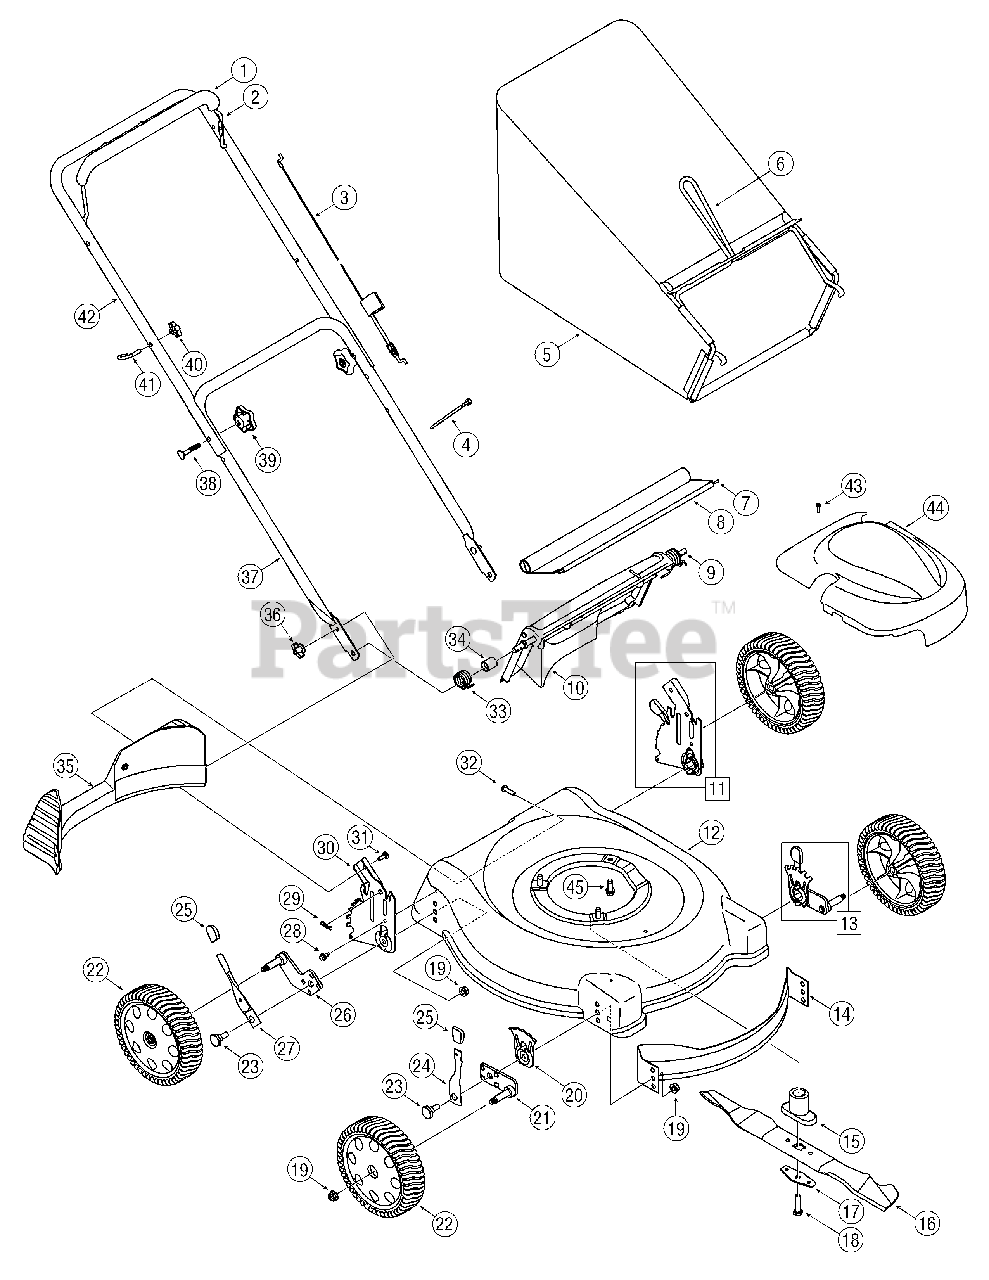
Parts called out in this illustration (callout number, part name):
1	Blade Control Handle Cover
3	Control Cable - 40"
4	Cable Tie
5	Grass Bag Assembly
7	Trailshield Wire
8	Trailshield
9	Rear Door Pivot Rod
10	Rear Discharge Door
11	Handle Bracket Assy - RH
11	Handle Bracket Assy - LH
13	Height. Adj. Assy. Front - RH
13	Height Adj. Assy. Front - LH
14	Front Baffle
15	Blade Adapter
16	Blade
17	Bell Blade Support
18	HH Cap Screw, 3/8-24 x 2.50
19	Flange Lock Nut, 3/8-16
20	Height Adjustment Plate
21	Pivot Arm Assembly - LH
21	Pivot Arm Assembly - RH
22	Wheel, 8 x 2.125 Gray Idle S-Wave
23	Shoulder Screw .500 x .434
24	Spring Lever
25	Height Adjustment Knob
26	Pivot Arm Assembly - LH
26	Pivot Arm Assembly - RH
27	Spring Lever
28	TT Screw 1/4-20 x .625
29	Hairpin Clip
30	Rear Handle Bracket - LH
30	Rear Handle Bracket - RH
31	Carriage Bolt, 1/4-20
32	HL Screw 1/4-15 x 1.00
33	Torsion Spring - LH
33	Torsion Spring - RH
34	Spacer
35	Rear Baffle
36	Wing Nut
38	Carriage Bolt, 5/16-18 x 2
39	Star Knob
40	Handle Knob
43	HL Screw #8-18 x 1.25
44	Engine Shroud
45	TT Screw 3/8-16 x 1
